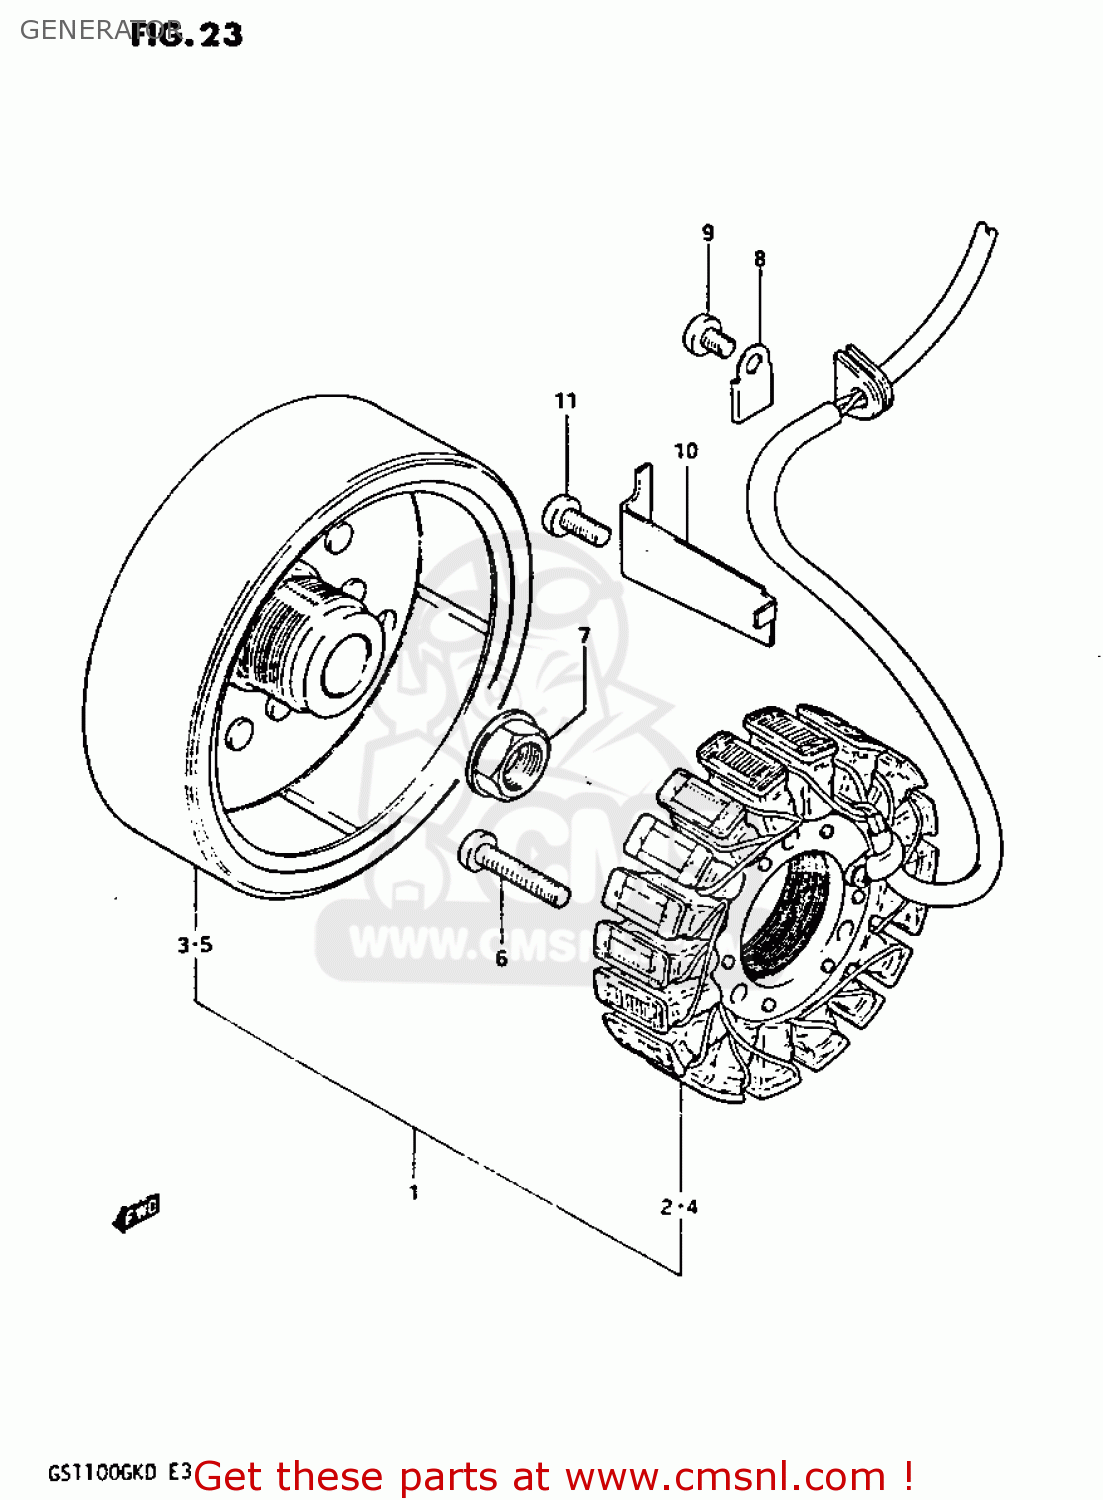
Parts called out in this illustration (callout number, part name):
1	STARTER ASSY
2	STARTER ASSY
3	ROTOR ASSEMBLY
4	STARTER ASSY
5	ROTOR ASSEMBLY
6	SCREW 6X30
7	NUT,GENERATOR ROTOR
8	CLAMP,GENERATOR LEAD WIRE
9	SCREW
10	CLAMP,GENERATOR LEAD WIRE
11	SCREW
